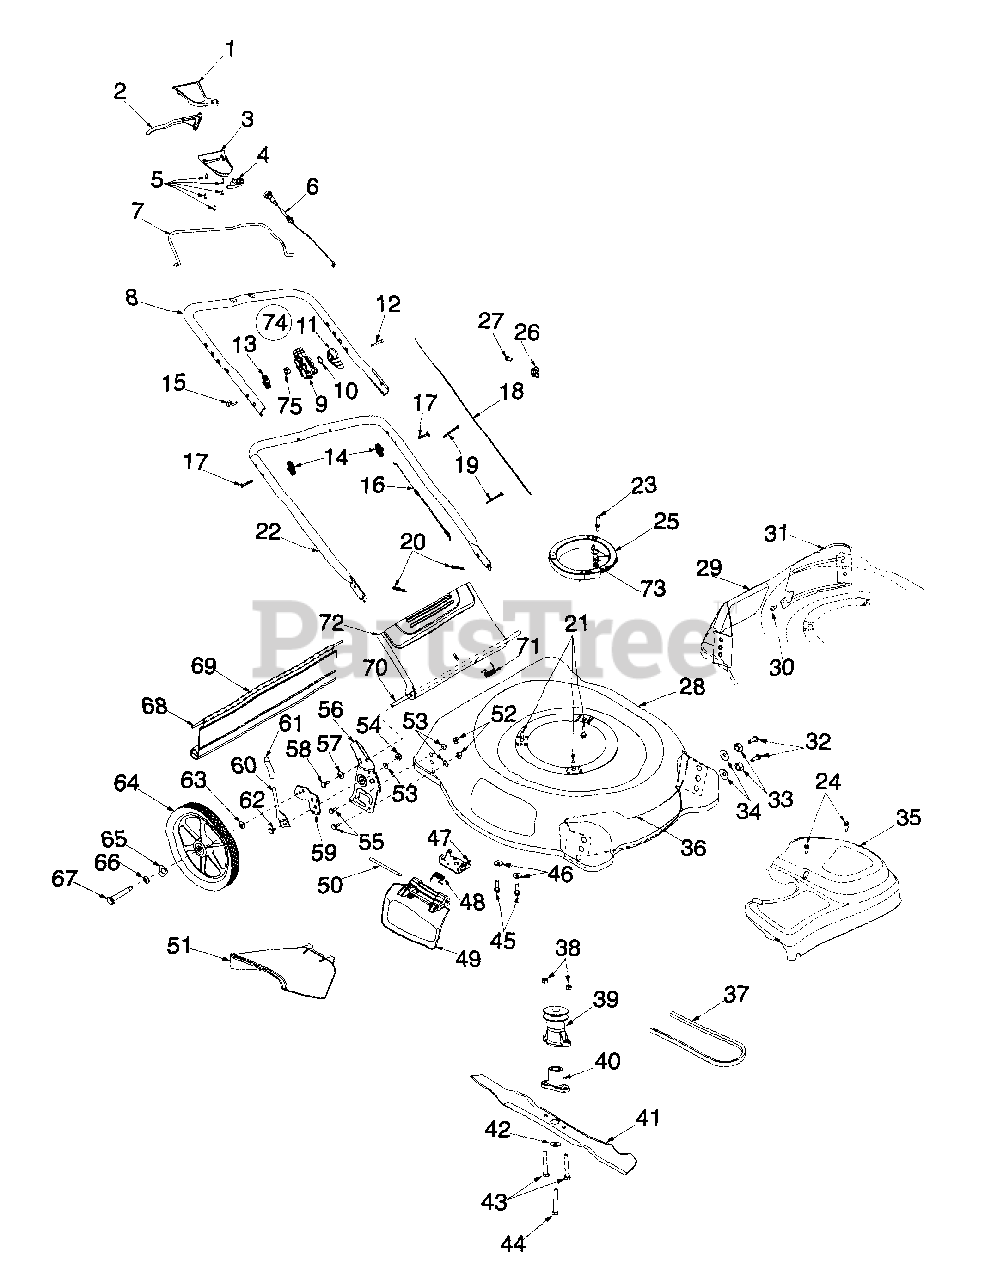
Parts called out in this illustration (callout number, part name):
1	Upper Drive Cover
2	Drive Lever
3	Lower Drive Cover
4	Mounting Cap
5	Screw #10-16 x .625
6	Drive Cable
9	Throttle Hsg.
10	Curved Washer .663 x .980 x .014
11	Throttle Lever
11	Screw Oval C-Sunk 1/4-20 x 1.31
12	Screw Oval C-Sunk 1/4-20 x 1.81
14	Knob
15	Eye Bolt 1/4-20
16	Throttle Cable: 55"
17	Carriage Bolt 5/16-18 x 2.0
18	Control Cable: 39"
19	Tie Cable
20	Cotter Pin
21	Tapp Screw w/ Hex Lock Wash
23	Pin-Belt Keeper
24	Screw #12 x .457
25	Engine Spacer
26	Cable Clamp
27	Hex Screw: T: #10-32 x .625 Lg.
30	Scr:AB:1/4-14:.625: Trustrx
32	Hex Screw 3/8-16 x .75
33	Bell Wash .39 x 1.13 x .062
34	Hex Nut 3/8-16 (Gr. 5)
35	Trans Cover - Black
38	Hex Lock Nut 1/4-20
39	Drive Pulley
40	Blade Adapter Kit
41	21" Mulching Blade
42	Bell Washer .396 I.D. x 1.140 O.D. x .095
43	Hex Screw 1/4-20 x 1.50
44	Hex Screw 3/8-24 x 2.50
45	Tapp Screw 1/4-20 x .500
46	Bell Wash .265 x .75 x .062
48	Torsion Spring .290 ID x 1.95
49	Mulch Plug Ass'y.
50	Hinge Pin
51	Chute Deflector
52	Hex Nut 3/8-16 (Gr. 5)
53	Bell Wash .39 ID x 1.38 OD
54	Hex Flange Lock Nut 3/8-16
55	Hex Screw w/wash 1/4-14 x .625
57	Bell Wash .265 x .75 x .062
58	Hex Screw TT 1/4-20 x .500
59	Pivot Bar RH
60	Height Adj Lever
61	Foam Grip
62	Shldr Screw .500 Dia x .434
63	Wash. .401 x .870 x .063
64	Wheel Comp. 14 x 2 Yellow Link Tread
65	Spring Washer .50 ID x 1.0 OD
66	Flat Washer .510 x 1.373 x .04
67	Shldr Screw .500 x 2.62 3/8-16
68	Wire
69	Rear Flap
70	Pivot Rod
71	Torsion Spring
74	Throttle Comp.
75	Hex Lock Nut 1/4-20
